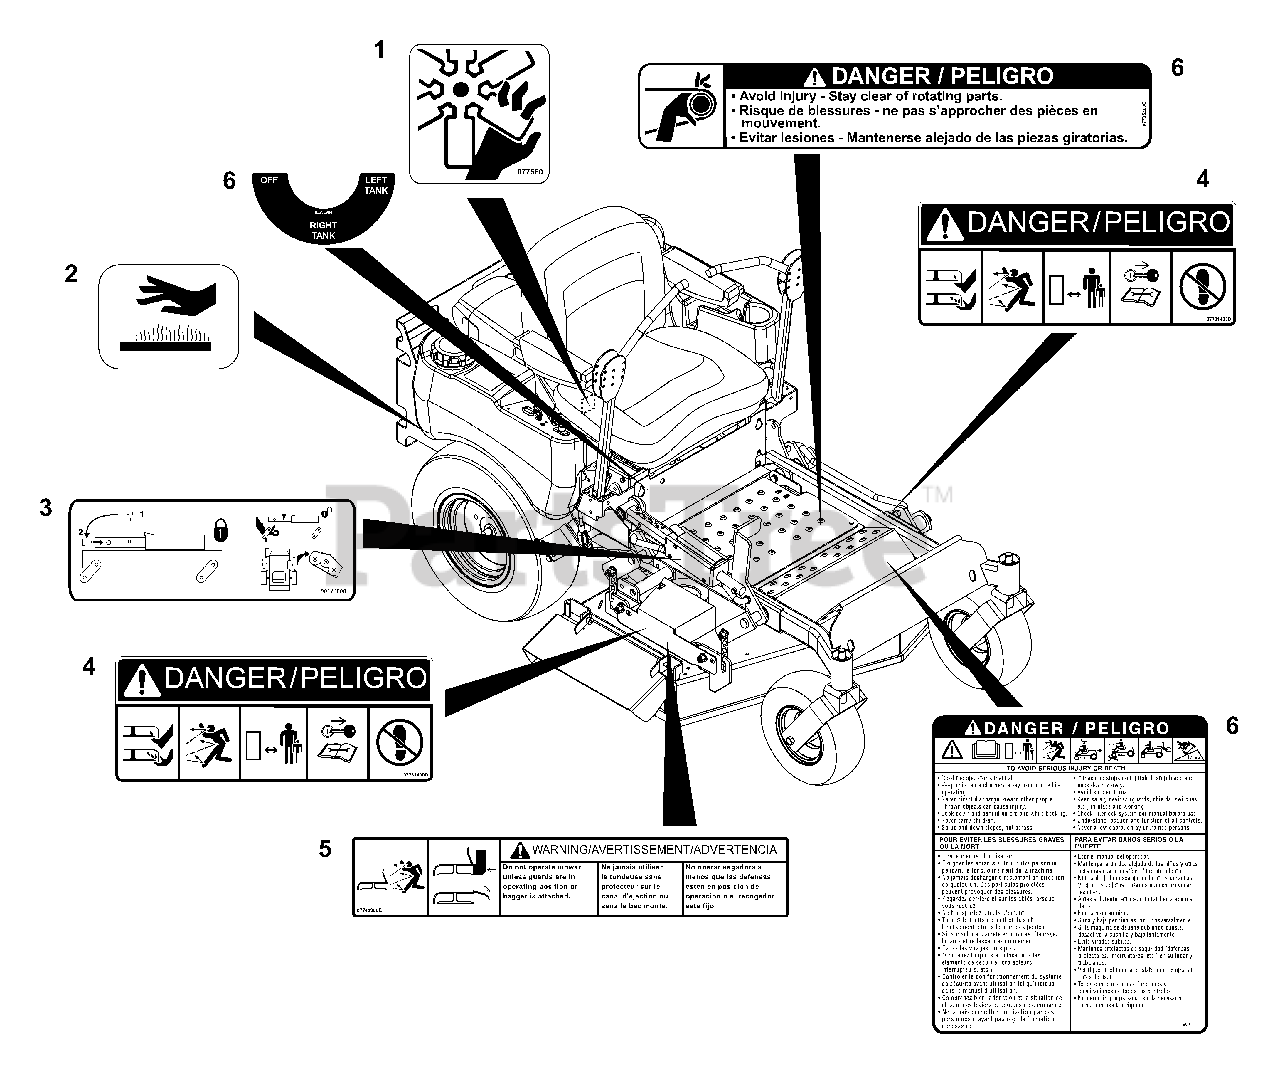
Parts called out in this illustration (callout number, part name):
1	Decal, Danger Fan
2	Decal, Hot Surface
3	Decal, Deck Service
4	Decal, Mower Pan Head Danger
5	Decal, Warning
6	Set, Decal Common Danger/Fuel
